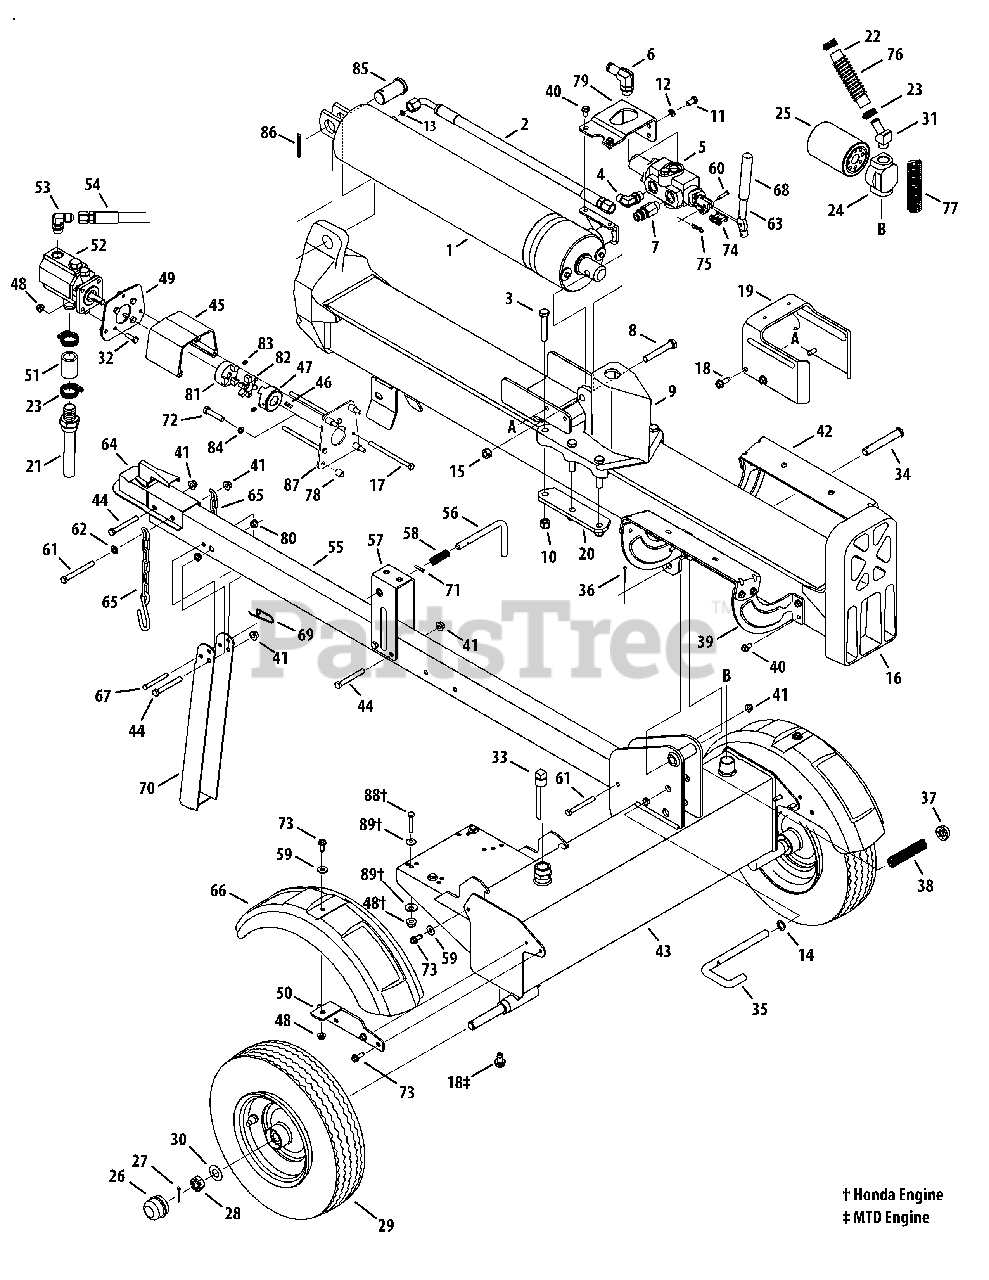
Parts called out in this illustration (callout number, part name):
2	Hydraulic Tube
3	Hex Cap Screw, 1/2-20 x 2.75
4	90 Degree Solid Adapter
5	Control Valve
6	Return Elbow
7	Nipple Pipe, 1/2-14
8	Hex Cap Screw, 1/2-13 x 3.25
9	Wedge Assembly
10	Hex Lock Nut, 1/2-20
11	Hex Cap Screw, 3/8-16 x .75
12	Lock Washer, 3/8
13	O-Ring, .489 ID x .070 Dia.
14	Flat Washer, .635 x.93 x.06
15	Hex Lock Nut, 1/2-13
16	Beam Assembly
17	Hex Screw, 5/16-18 x 5.50
17	Hex Screw, 5/16-18 x 4.75
18	Self Tapping Screw, 3/8-16 x 1.0
19	Dislodger Bracket
21	Inlet Filter
22	Return Hose, 3/4 x 44
23	Hose Clamp, 5/8
24	Filter Housing
25	Oil Filter
27	Cotter Pin
28	Slotted Nut, 3/4-16
29	Complete Wheel Assembly
29	Dust Seal
29	Roller Bearing
30	Flat Washer, .760 x 1.500
31	Hydraulic Fitting, 1 1/16 Orb x .75
32	Hex Screw, 5/16-18 x 1.00
33	Vented Dipstick
34	Clevis Pin
36	Cotter Pin
38	Compression Spring
39	Log Tray Bracket
40	Hex Washer Screw, 5/16-18 x .750
41	Flange Lock Nut, 3/8-16
44	Hex Bolt, 3/8-16 x 3
45	Coupling Shield
46	Square Key, 1/4 x 2.00
46	Square Key, 3/16 x .75
47	Coupling, 1.00
47	Coupling, .875
48	Flange Lock Nut, 5/16-18
49	Rear Coupling Support Bracket
50	Fender Mounting Bracket
53	Hydraulic Fitting, 7/8 Orb x .8125
54	High Pressure Hydraulic Hose
55	Tongue Assembly
56	Latch Rod
58	Compression Spring
59	Flat Washer
60	Clevis Pin
61	Hex Cap Screw, 3/8-16 x 3.50
62	Flat Washer, .375 x.738 x.063
63	Hydraulic Valve Control
64	Hitch Coupling Assembly
67	Clevis Pin
69	Spring Pin
71	Spiral Pin
72	Hex Cap Screw, 3/8-16 x 1.75
72	Hex Cap Screw, 5/16-24 x .75
73	Self-Tapping Screw, 5/16-18 x 1.00
74	Valve Handle Link
75	Cotter Pin, Bow Tie
76	Hose Guard, 44"
77	Hose Guard, 48"
78	Spacer, .385 x .623 x .75 LG
79	Outer Valve Bracket
80	Plastic Bushing, .380 ID
81	Coupling, .500
82	Spider Bushing
83	Set Screws
84	Lock Washer, 3/8
84	Lock Washer, 5/16
85	Clevis Pin, 1.25 x 2.50
86	Cotter Pin, 3/16 x 2
87	Front Coupling Support Bracket
88	Hex Cap Screw 5/16-18 x 1.75
89	Bell Washer, .340 x .872 x .060
